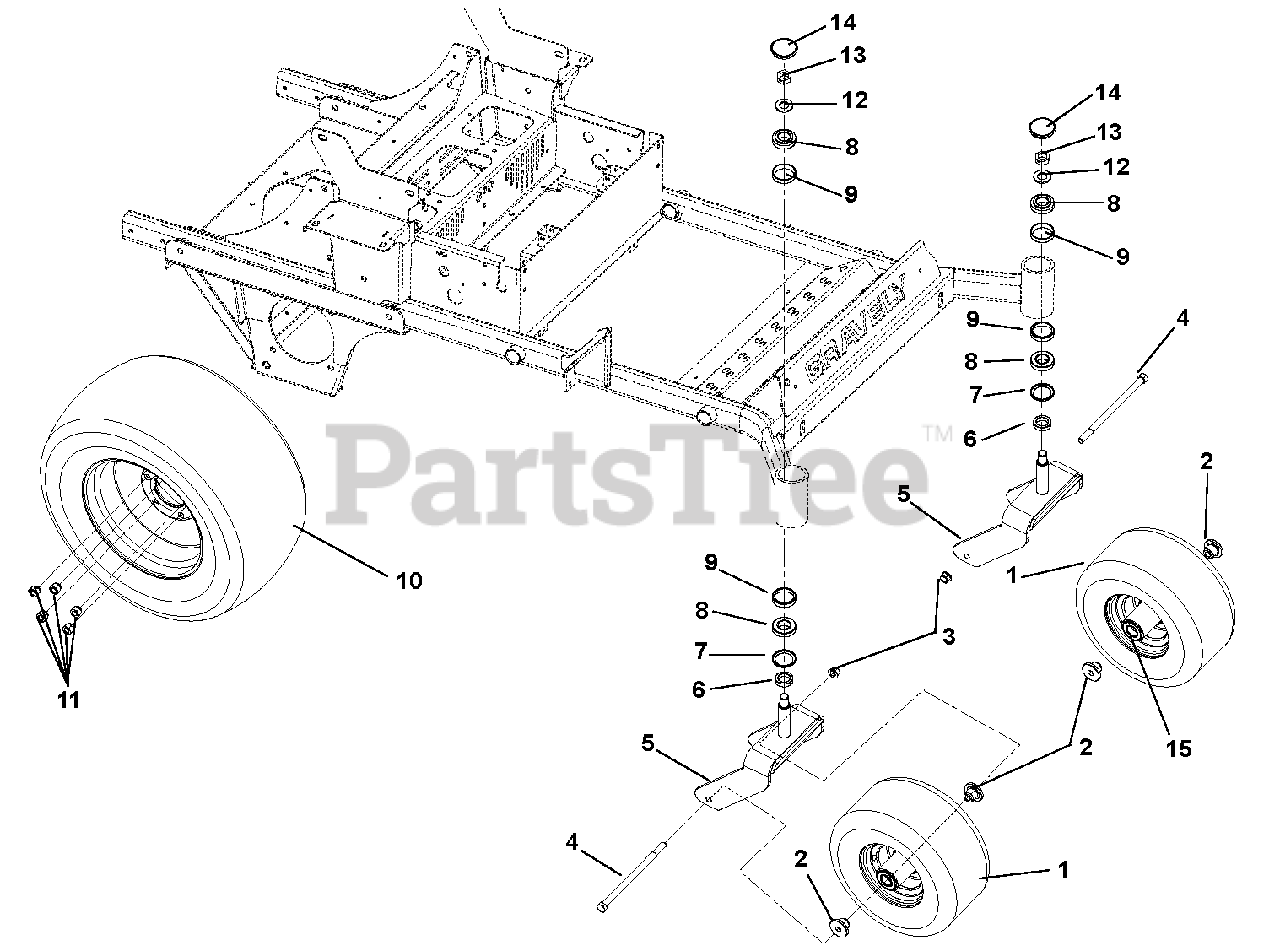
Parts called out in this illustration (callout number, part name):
1	Tire/Wheel Assembly, 15 x 6.00-6 Smooth
2	Spacer, Front Wheel
3	Nut, .50-13 Nyloc Flange
4	Bolt, Hex .50-13 x 9.00 Grade 5
5	Caster Fork Weldment
6	Spacer 1.258 x 1.75 x .550
7	Seal, Oil 1.75 x 2.332 x .312
8	Bearing, Cone 1.25 x .66
9	Bearing, Cup 2.328 x .465
10	Tire/Wheel Assembly, 23 x 10.5-12
11	Nut, Wheel .50-20 13/16 Across Flats Automotive Type
12	Washer, Flat Steel .812 x 2.00 x .148
13	Nut, Jam Center Lock .75-16
14	Cap, Dust
15	Bearing, 25 mm ID x 52 mm OD x 15 mm
